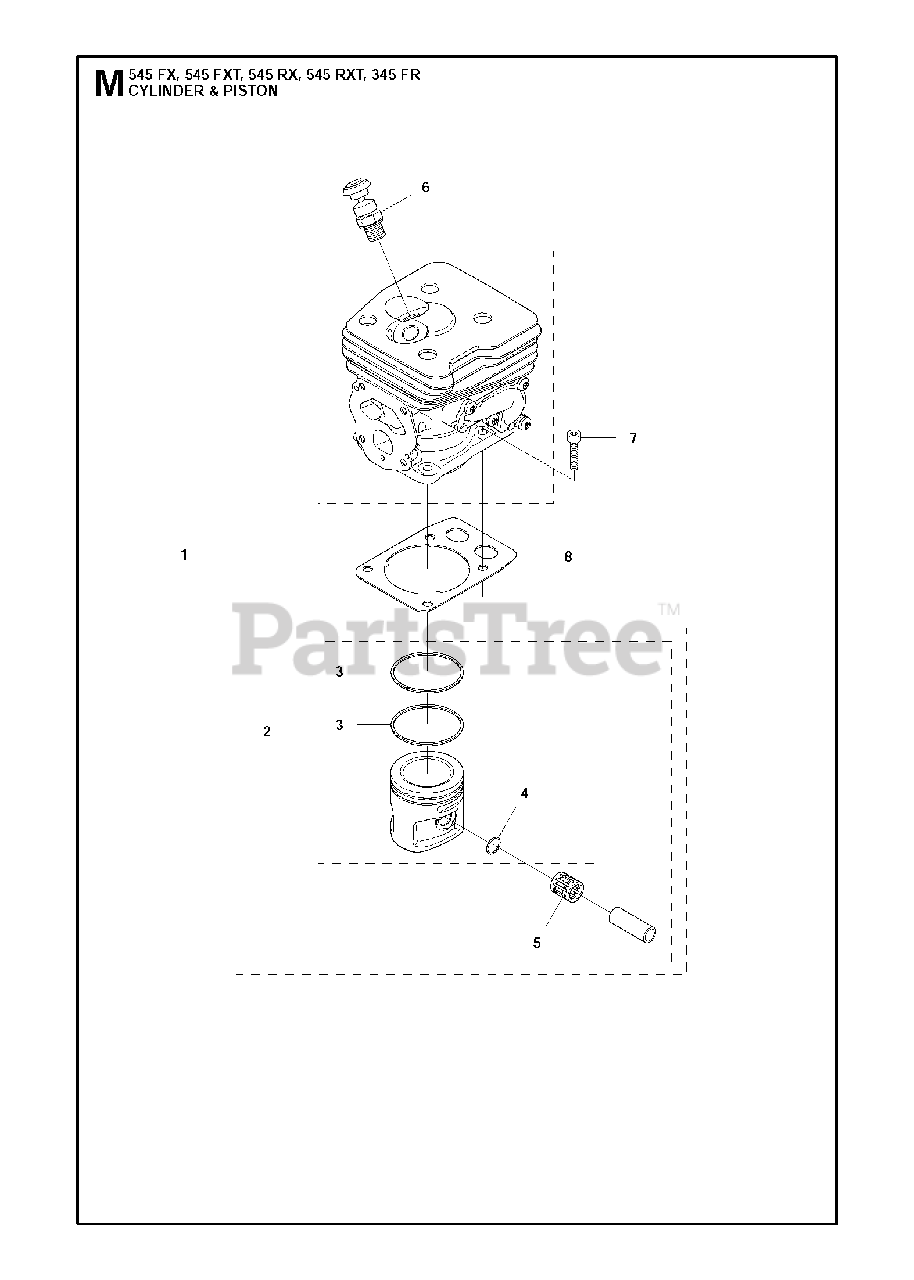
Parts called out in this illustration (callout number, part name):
1	CYLINDER
2	RP PISTON ASSY
2	PISTON ASSY
3	PISTON RING D42
3	PISTON RING
4	LOCKING RING
5	NEEDLE BEARING
6	DECOMPRESSION VALVE
7	SCREW MC6S 5X20
8	GASKET CYLINDER
